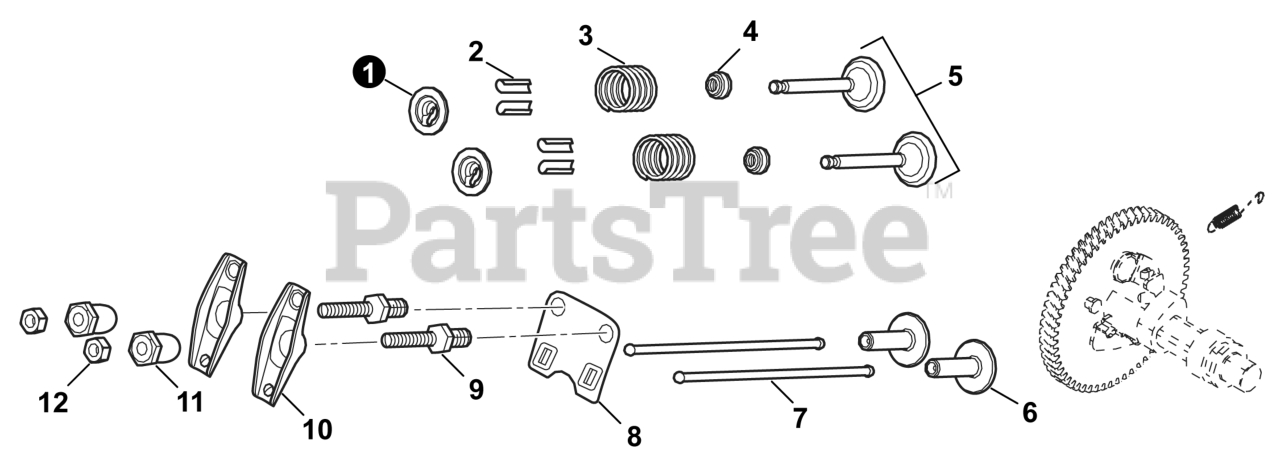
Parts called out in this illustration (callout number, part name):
1	SEAT, VALVE SPRING
2	CLAMP, VALVE LOCK
3	SPRING, VALVE
4	SEAL, GUIDE
5	VALVES SET, INTAKE/EXHAUST
6	TAPPET, VALVE
7	ROD, PUSH
8	PLATE, LIFTER STOPPER
9	BOLT, ROCKER SHAFT
10	ARM, ROCKER
11	NUT, VALVE ADJUSTING
12	NUT, VALVE LOCK
